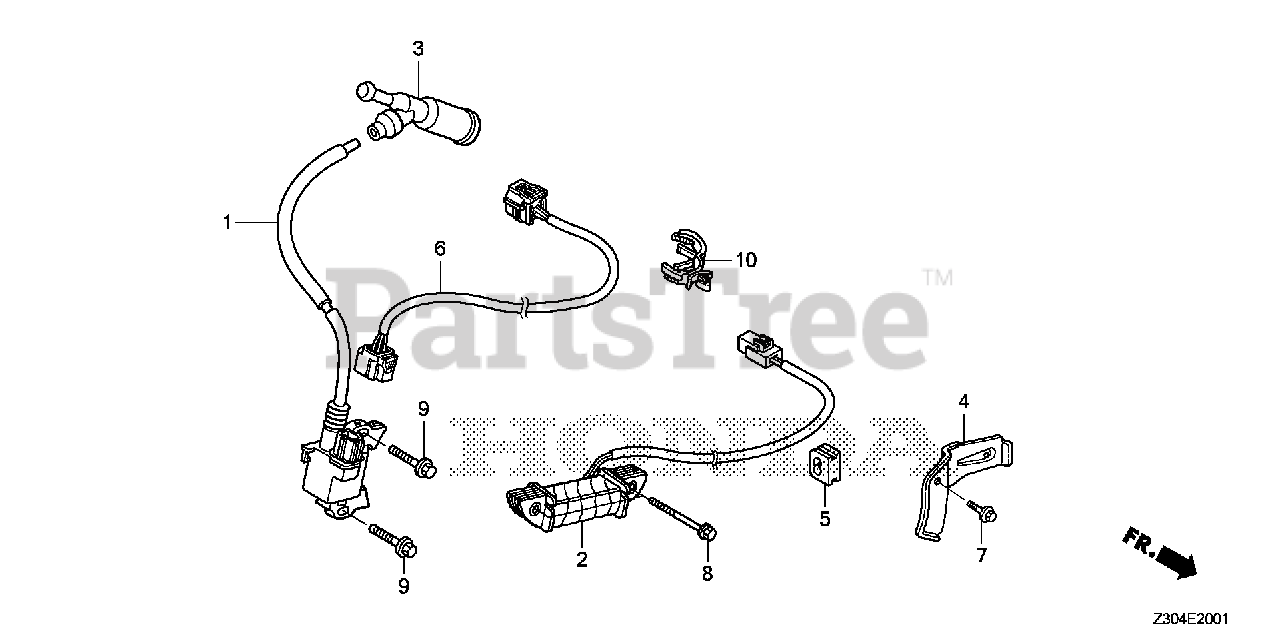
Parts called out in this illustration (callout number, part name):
1	COIL ASSY., IGNITION
2	COIL ASSY., POWER
3	CAP ASSY., NOISE SUPPRESSOR (NGK Y-EZD)
4	CLAMP, WIRE
5	GROMMET, WIRE
6	WIRE HARNESS ASSY., ENGINE
7	BOLT, FLANGE (6X12) (CT200)
8	BOLT, FLANGE (6X32) (CT200)
9	BOLT, FLANGE (6X28) (CT200)
10	CLIP, HARNESS
